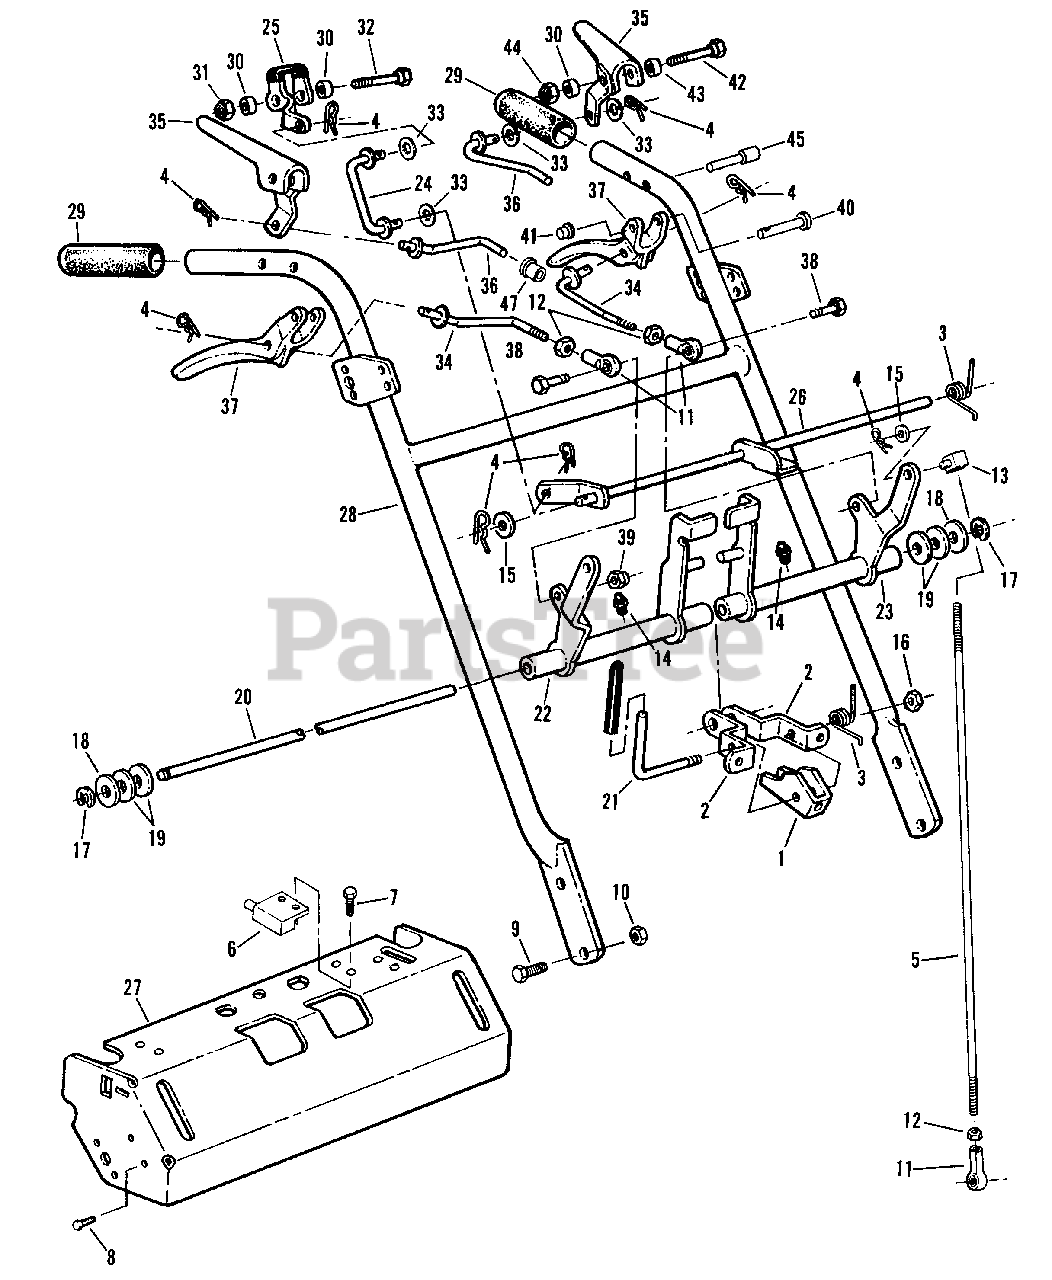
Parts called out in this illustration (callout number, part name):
1	LATCH
2	BRACKET, Neutral Mounting
3	SPRING, Neutral Torsion
4	PIN, Hair
5	ROD, Traction
6	SWITCH
7	SCREW, #12-14 x 1/2" Self-Tapping
8	SCREW, 1/4-20 x 1/2" Self-Tapping
9	SCREW, 3/8-16 x 1" Hex Head Cap
10	NUT, 3/8-16 Hex (Nyloc)
11	BALL JOINT LINKAGE, 5/16-24
12	NUT, 5/16-24 Hex
13	SWIVEL
14	FITTING, 1/4-28 Zerk
15	WASHER, 3/8" Flat
16	NUT, 1/4-20 Hex (Nyloc)
17	"E" RING 1/2
18	BUSHING 1/2 Machinery
19	WASHER, 1/2 Flat
20	ROD, Pivot
21	INDICATOR, Neutral
22	WELDMENT, Speed Control (Left Hand)
23	WELDMENT, Speed Control (Right Hand)
24	ROD, Neutral Release
25	RELEASE, Neutral
26	WELDMENT, Neutral Paddle
27	CONSOLE (Pistol Grip)
28	WELDMENT, Handle
29	GRIP
30	SPACER, .259 ID x .78" Long
31	NUT, 1/4-20 Hex Lock
32	SCREW, 1/4-20 x 2-3/4"
33	WASHER, 5/16 x 1/2" O.D. (Stainless)
34	ROD, Drive (Left Hand)
35	WELDMENT, OPC (Left Hand)
36	ROD, OPC (Left Hand)
37	LEVER, Drive
38	SCREW, 5/16-18 x 1"
39	NUT, 5/16-18 Hex (Nyloc)
40	PIN, 3/16 x 1-3/4" Clevis
41	NUT, 3/16 Push
42	BOLT, 1/4-20 x 2-3/4"
43	BUSHING
44	NUT, 1/4-20 Hex
45	PIN, 5/16 x 1-1/8" Split
47	BUSHING 5/16 (Plastic)
